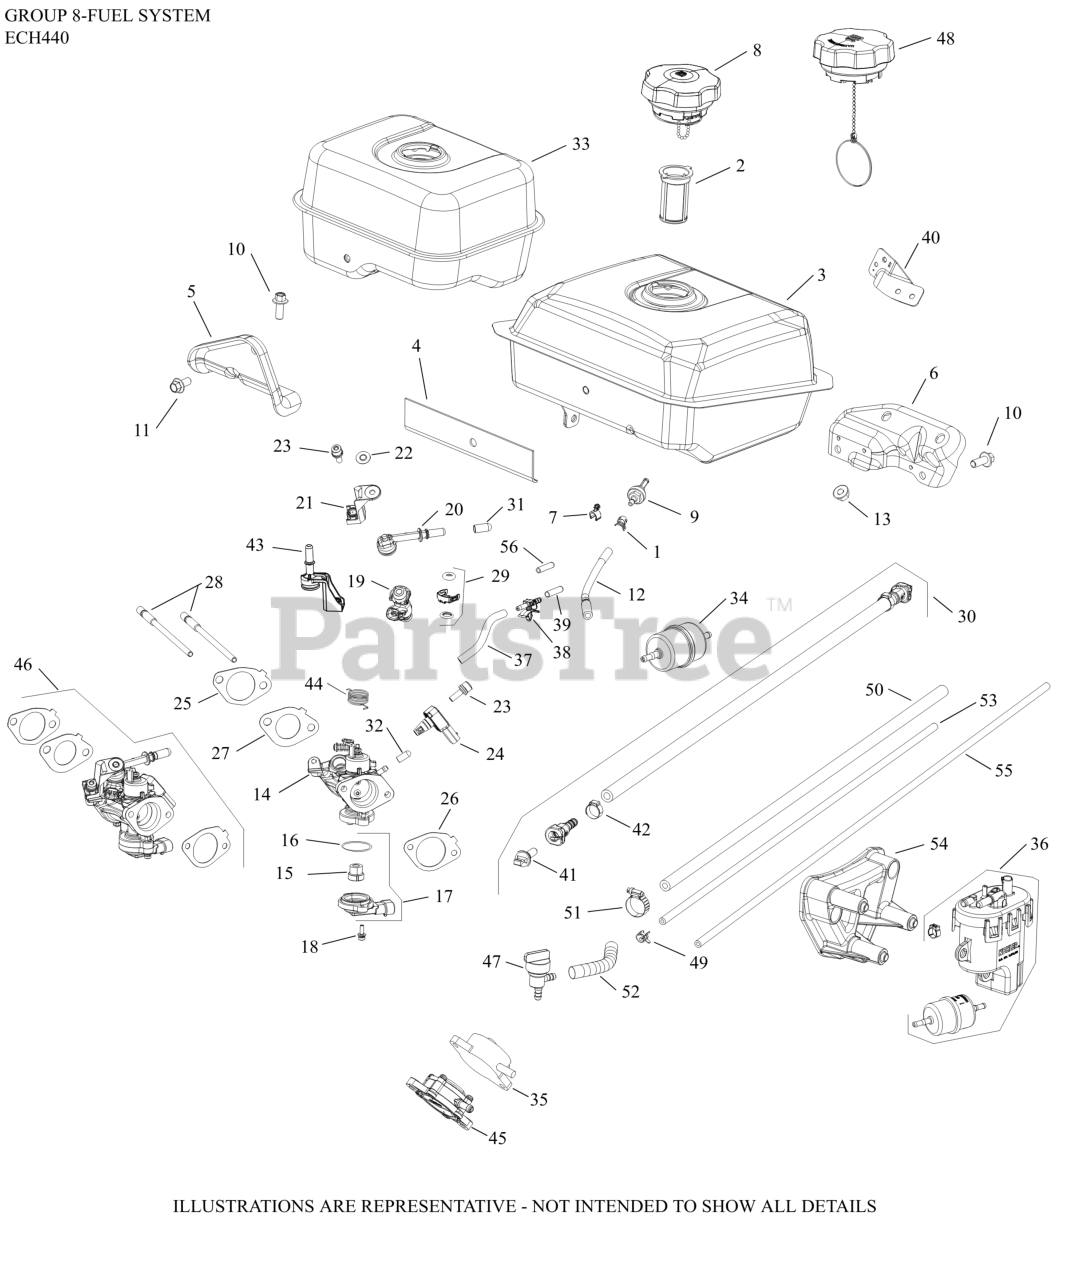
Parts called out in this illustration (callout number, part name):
1	CLAMP, FUEL LINE
2	FILTER, FUEL TANK
3	TANK, FUEL
5	BRACKET, FUEL SUPPORT
6	BRACKET, FUEL SUPPORT ASSEMBLY
8	CAP, EVAPORATIVE EMISSIONS-(#1717343S)
8	FUEL CAP, ASSEMBLY-USE 17 173 49-S
9	FITTING, FUEL ASSY
10	SCREW, M8 X 20
11	SCREW, FLG 8X1.25X16
12	HOSE, FUEL LOW-PERMEATION
13	NUT, FLG M8X1.25
14	KIT, THROTTLE BODY AND GASKETS
18	SCREW, HEXALOBULAR M4 X 0.7 X SEMS
19	INJECTOR, FUEL
20	CAP, FUEL INJECTOR
21	BRACKET ASSEMBLY, FUEL CAP
22	CLIP, RETAINER
23	SCREW, HEXALOBULAR M6 X 1 SEMS
24	SENSOR, T-MAP
25	KIT, GASKET INTAKE
26	GASKET, THROTTLE BODY
27	GASKET, INSULATOR TO T-BODY
28	STUD, INTAKE
29	KIT, FUEL INJECTOR O-RING
31	CAP, MASKING
32	CAP, MASKING
34	FILTER, FUEL
35	PUMP, FUEL
36	KIT,FP MODULE (ECH/ECV 440,630,940)
47	FUEL SHUTOFF, SWITCH
48	CAP, FUEL ASSEMBLY
49	CLAMP, HOSE
50	HOSE,LW PERM.FUEL 24.00"-USE 25 111 81-S
51	CLAMP, HOSE (KM)-USE 25 237 31-S
52	SLEEVE, ANTI ABRASION-USE 25 431 12-S
55	HOSE, EVAPORATIVE
56	CAP, MASKING
